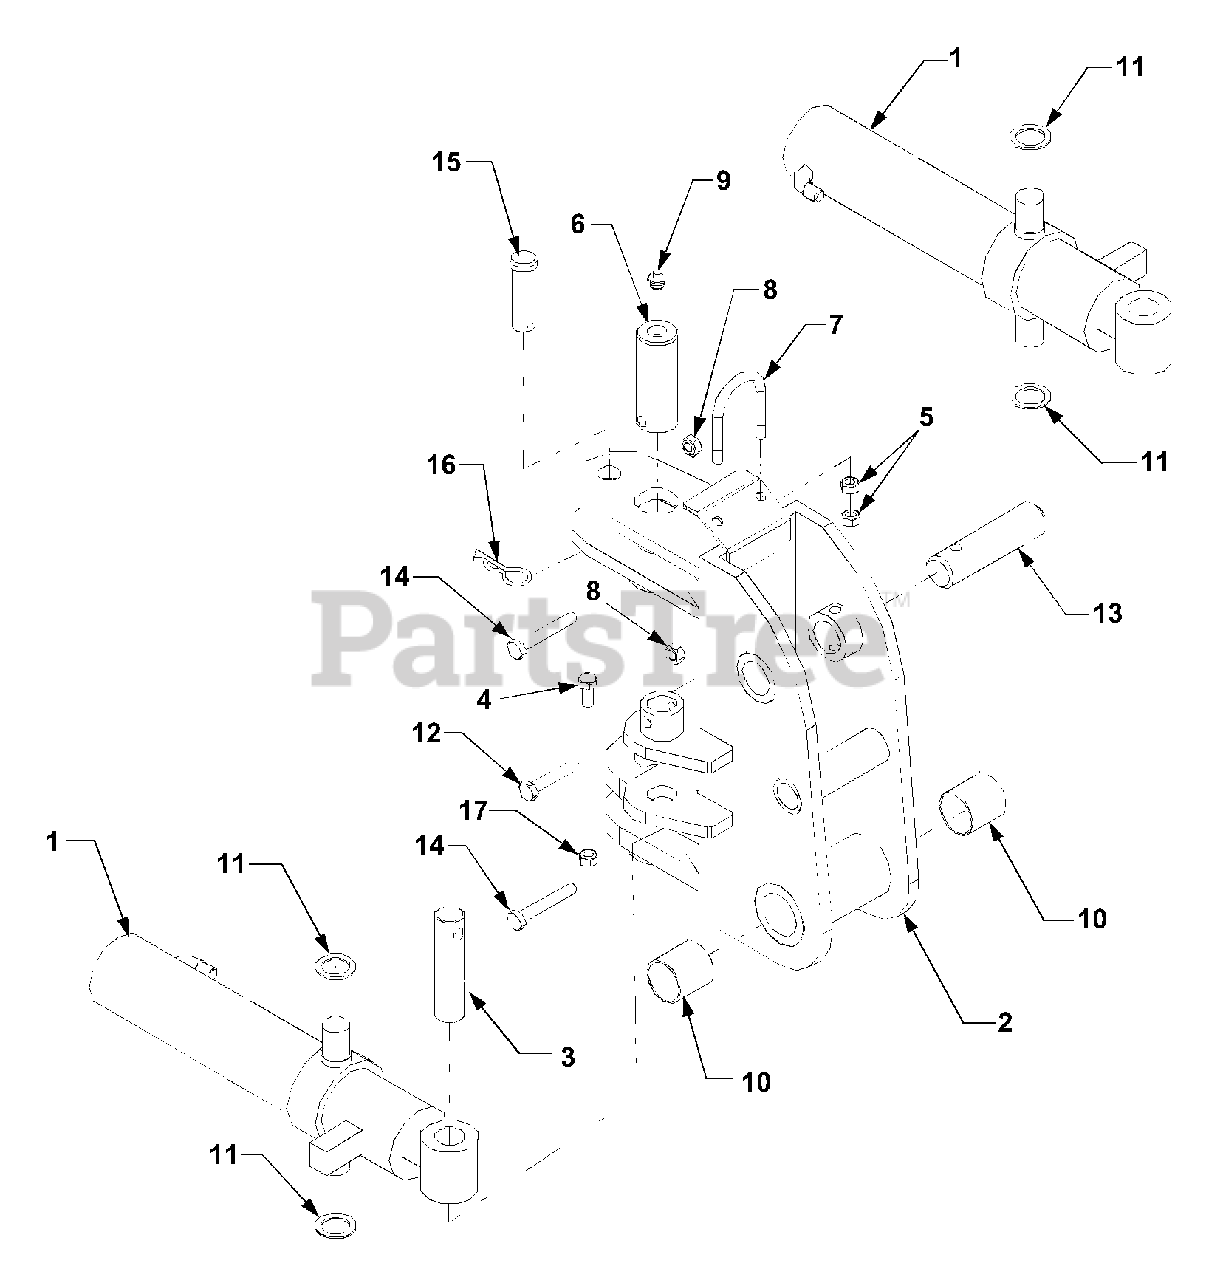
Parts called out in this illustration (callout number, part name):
1	Cylinder Ass'y. - Swing
2	Swing Frame Ass'y.
4	Hex Head Screw, M8 x 50
5	Hex Nut, 5/16-18
7	U-Bolt, 5/16-18
8	Hex Nut, M10 Lock
9	Grease Nipple
12	Hex Head Screw, M10 x 50
14	Hex Head Screw, M10 x 60
17	Hex Nut, M8 Lock
